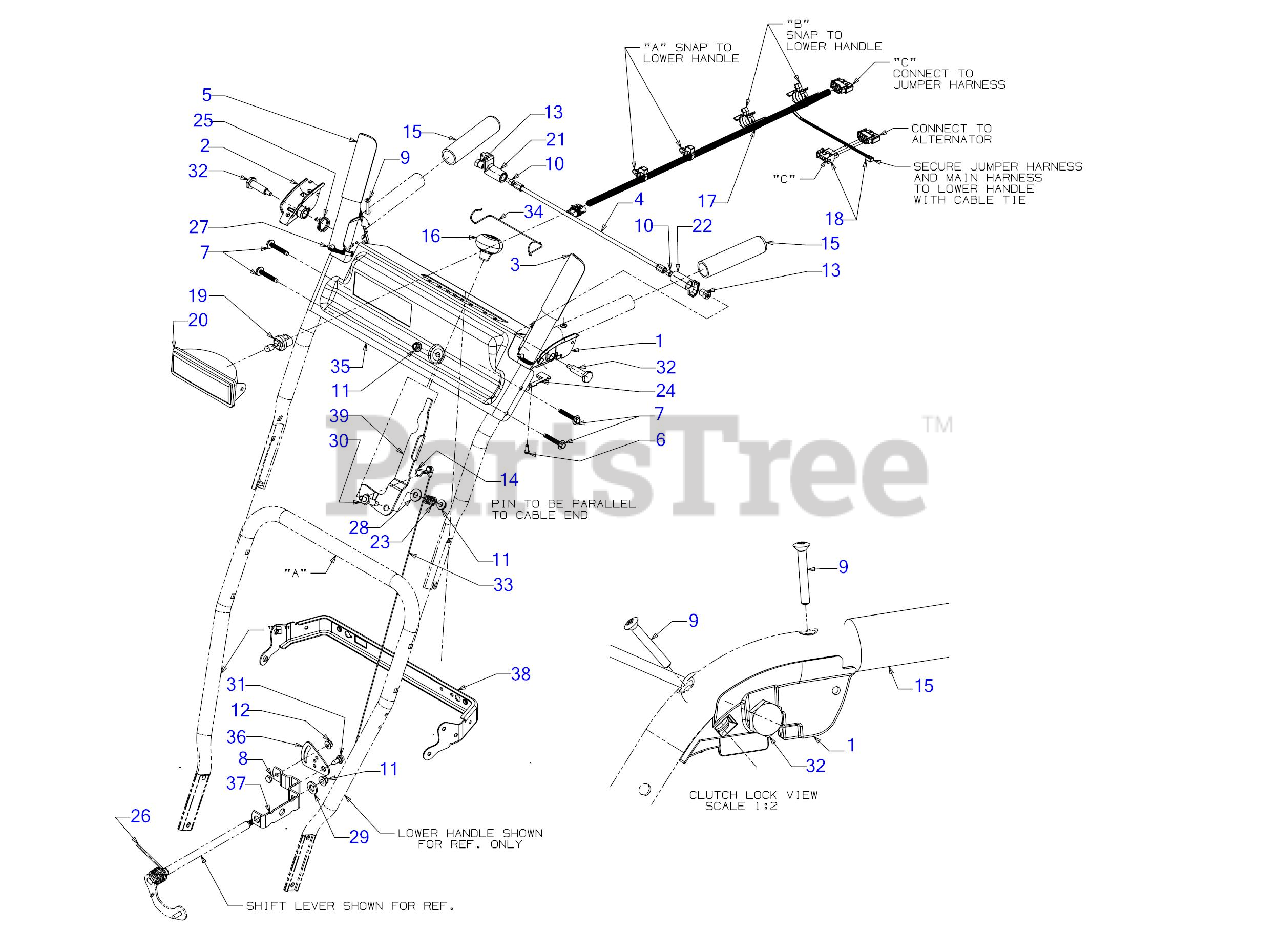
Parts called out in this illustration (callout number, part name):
1	CLUTCH LOCK HANDLE ASSEMBLY (LH)
2	CLUTCH LOCK HANDLE ASSEMBLY (RH)
3	HANDLE ASSEMBLY (LH)
4	PIVOT ROD
5	HANDLE ASSEMBLY (RH)
6	SCREW #8-16 x .50
7	SCREW 1/4-20 x 1.625
8	SCREW 1/4-20 x .620 GR5
9	SCREW #10-24 x 1.375
10	SCREW 1/4-20 x .50
11	FLANGE LOCK NUT 5/16-18
12	FLANGE LOCK NUT
13	HEX NUT W/PATCH
14	INTERNAL COTTER PIN
16	SHIFT KNOB
17	HALOGEN HEADLGHT HARNESS
18	DIODE JUMPER HARNESS
19	HALOGEN BULB
20	LAMP HOUSING
21	LOCK PLATE
22	CLUTCH LOCK CAM
23	COMPRESSION SPRING
24	CLUTCH SPRING
25	TORSION SPRING
26	TORSION SPRING
27	RUBBER BUMPER
28	FLAT WASHER .385X.870X.090
29	FLAT WASHER
30	SHOULDER BOLT
31	SHOULDER SCREW
32	SHOULDER SCREW .437 x 1.345 1/4-20
33	SPEED SELECTOR CABLE (STEEL)
34	RETAINER
36	PIVOT BRACKET
37	SHIFT SPEED BRACKET
38	HANDLE SUPPORT BRACKET
39	SPEED SHIFT LEVER
